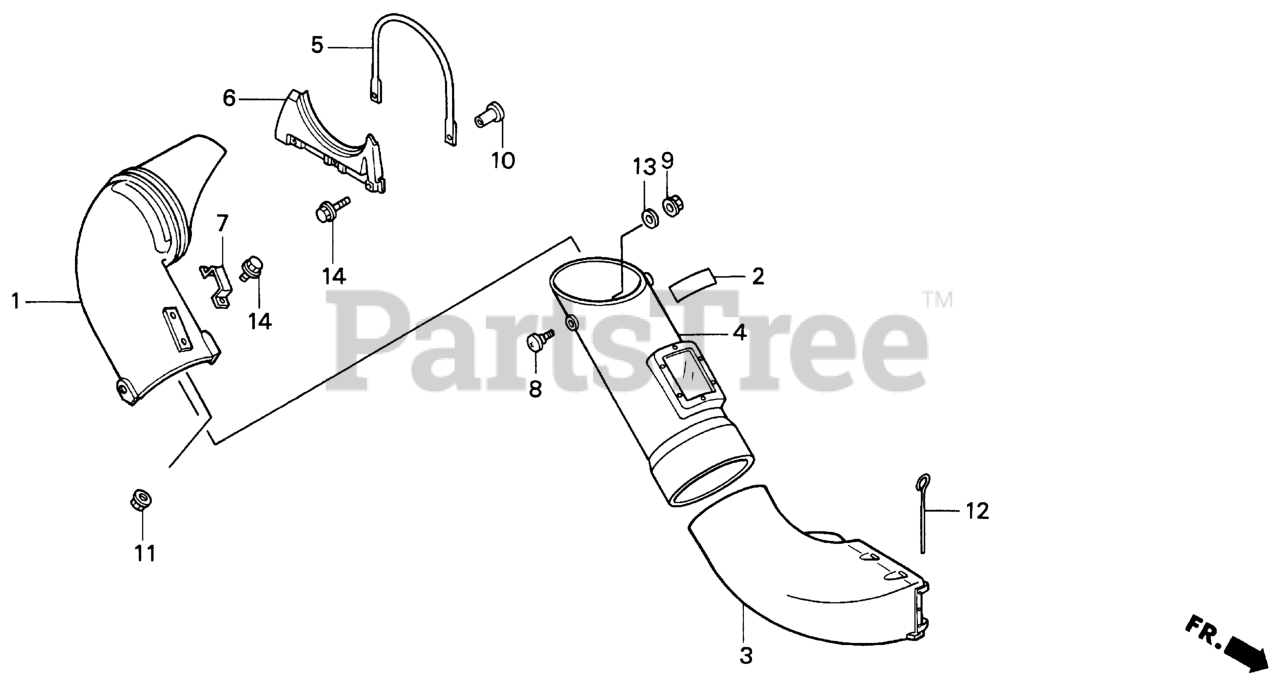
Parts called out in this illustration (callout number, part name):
1	CHUTE (UPPER)
2	LABEL, CHUTE (ENGLISH)
3	CHUTE (LOWER)
4	CHUTE, MIDDLE
5	SUPPORT, CHUTE
6	SEAL (NOT AVAILABLE)
7	HANDLE, CHUTE (NOT AVAILABLE)
8	BOLT, CHUTE
9	NUT, NYLON INSERT LOCK (8MM) (NOT AVAILABLE)
10	NUT, PIPE (6MM)
11	NUT, SELF-LOCK (6MM)
12	PIN, CHUTE (LOWER)
13	WASHER, PLAIN (8MM)
14	BOLT, FLANGE (6X16) Use from Engine SN 2056820.
